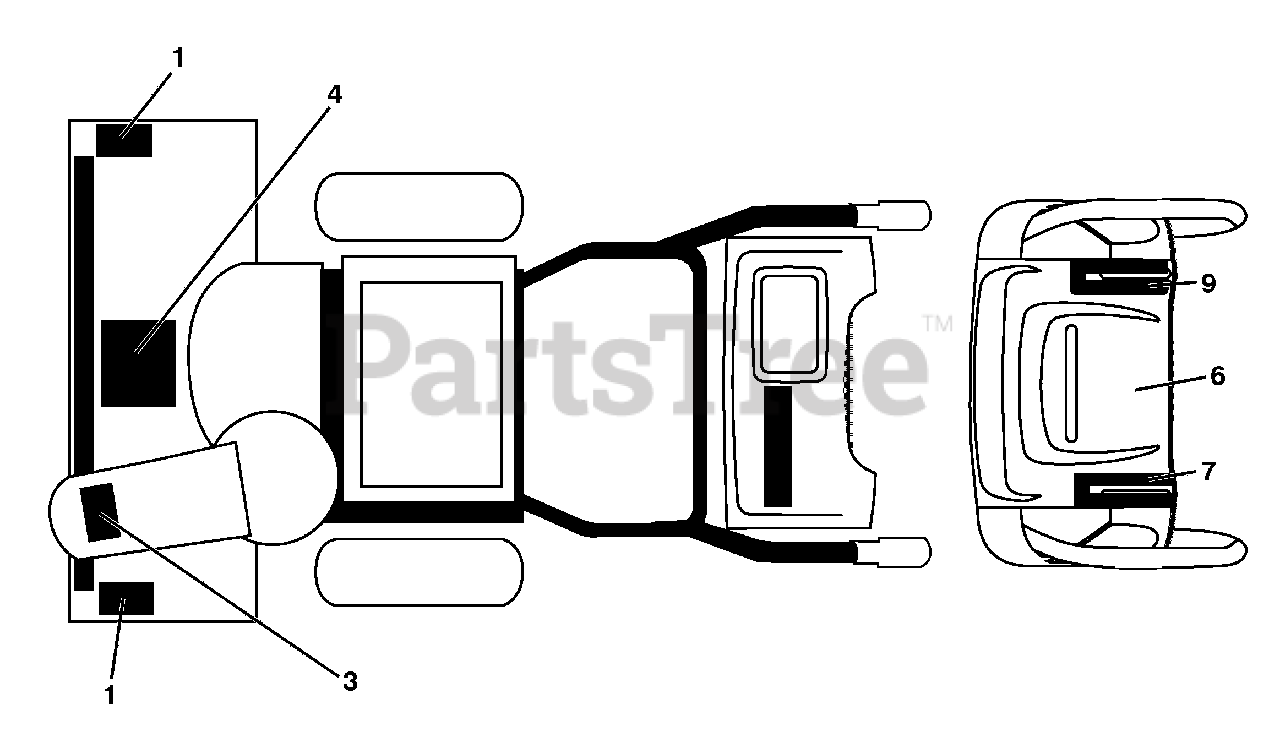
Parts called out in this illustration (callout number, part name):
1	Decal, Danger
3	Decal, Danger, Deflector
4	Decal, Danger
6	Decal, Instruction
7	Decal, Console, Lt Deflector Gray
9	Decal, Console, Rt Spd Gray
